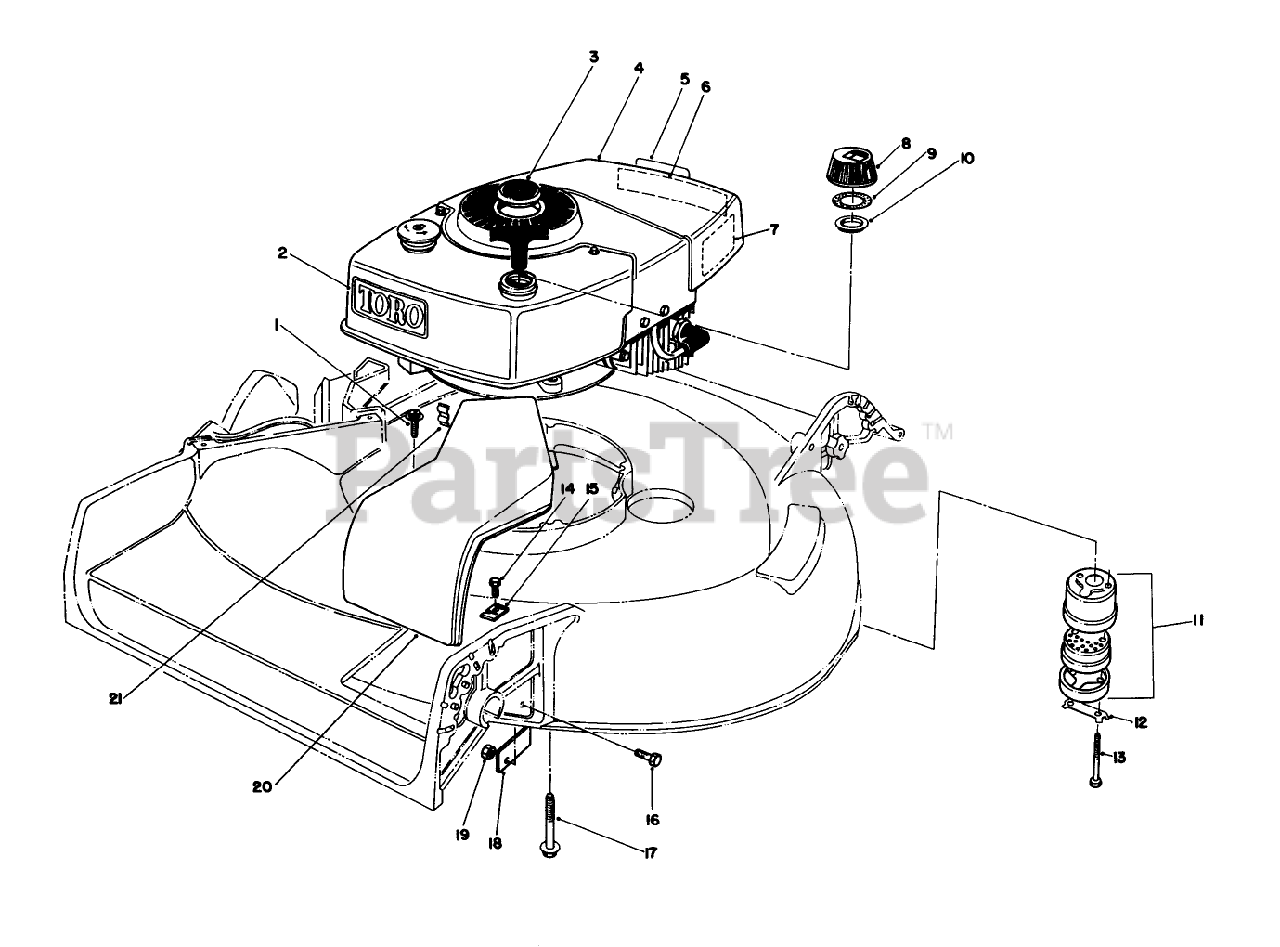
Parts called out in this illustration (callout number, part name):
1	SCREW
4	Engine
9	GASKET
11	MUFFLER ASM
12	CLIP - LOCKING
13	SCREW-HH
14	SCREW-THD ROLL, HWH
16	SCREW-HH
17	3/8-16 X 2-3/4 CAPSCR
19	NUT-LOCK, NI
